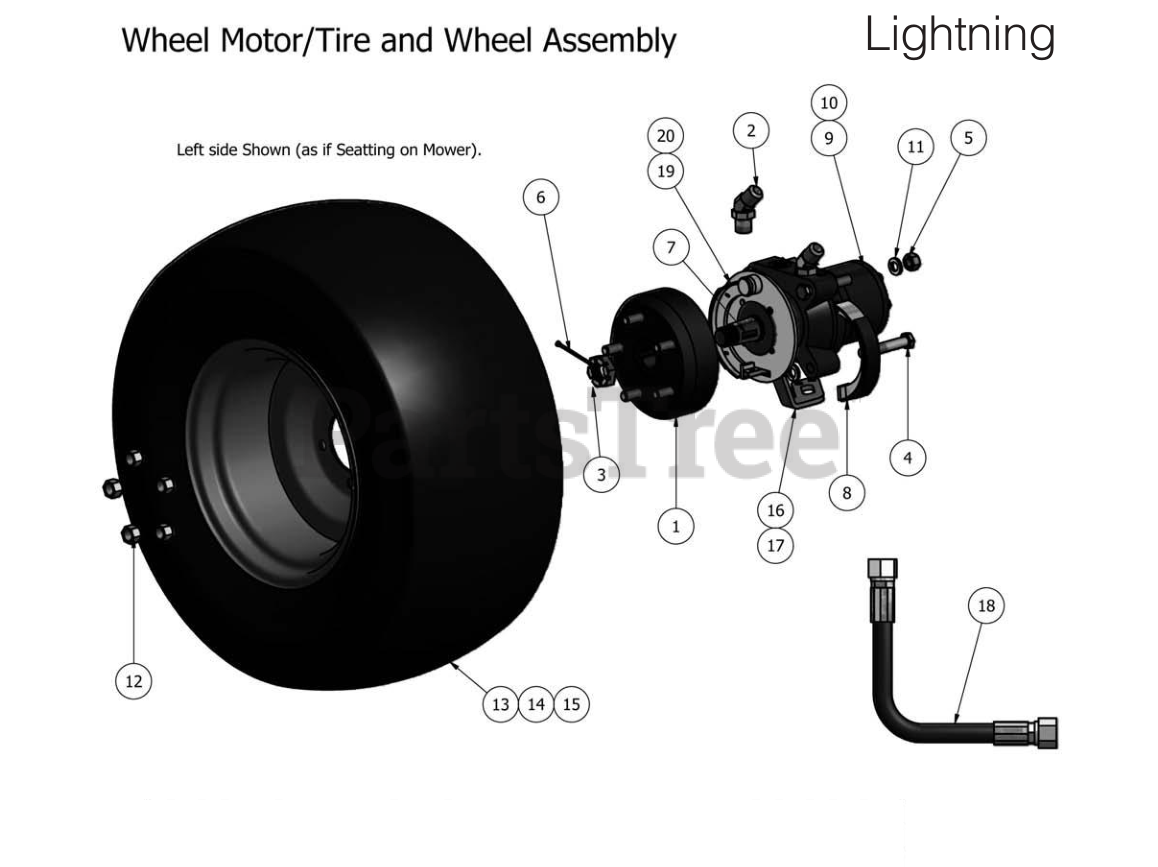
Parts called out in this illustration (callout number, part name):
1	Brake Drum
2	Hydraulic Fitting
3	1/2" Castle Nut
4	1/2" 13 x 3" GRS Hex Bolt Zinc
5	1/2" Hex Nut
6	1/8"x2 1/4" Cotter Pin
7	Woodruff Key
8	Brake Shoe
9	Wheel Motor 18cc Right Parker
10	Wheel Motor 18cc Left Parker
11	1/2" Lock Washer
14	26" x 12-12 Tire -60" & 72" Cut
15	26" Tire and Wheel Assembly
16	Brake Lever (wheel motor) Left
17	Brake Lever (wheel motor) Right
18	Hydraulic Hose
19	Left Brake Assembly
20	Right Brake Assembly
